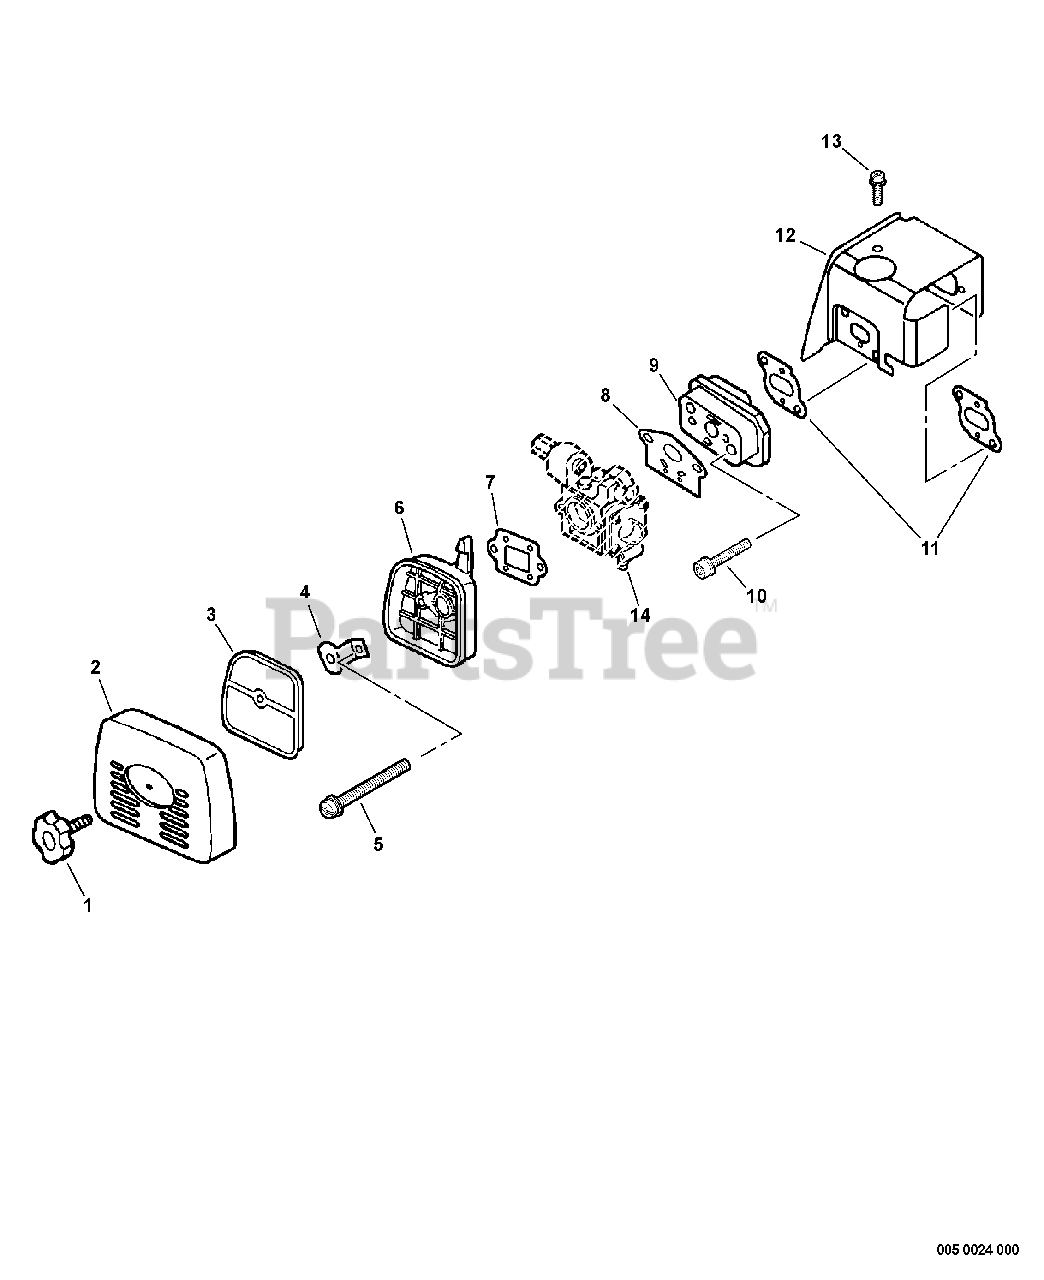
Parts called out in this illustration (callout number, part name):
1	THUMBSCREW
2	COVER, AIR FILTER
3	FILTER, AIR - HEAVY DUTY
4	PLATE, PREVENT
5	SCREW - 5X60
6	CASE, AIR FILTER
8	GASKET, INTAKE
9	INSULATOR, INTAKE
10	SCREW - 5X25
11	GASKET, INTAKE
12	SHIELD, CYLINDER
14	CARBURETOR
15	RePower TUNE-UP KIT
16	RePower TUNE-UP KIT
